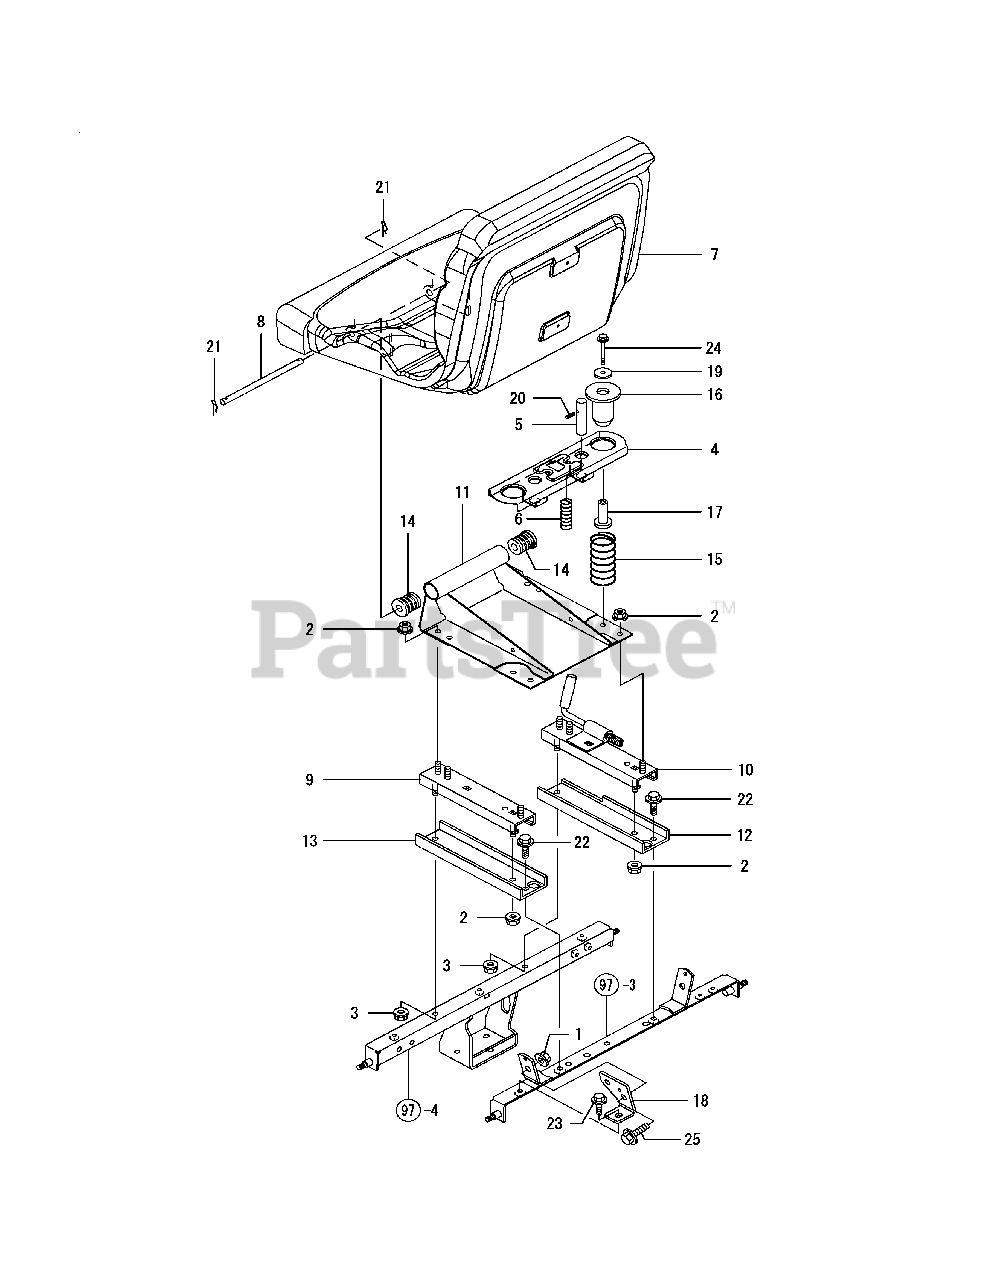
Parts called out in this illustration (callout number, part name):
1	NUT, M10
2	NUT W/WASHER 8
3	NUT W/WASHER 8
4	BKT (SEAT SPRING)
9	ADJUSTER, BELT
10	ADJUSTER, BELT
11	LOWER BRACKET, SEAT
15	SPRING, CUSHION
16	RUBBER, CUSHION
18	STAY, SEAT BELT L
19	WASHER 8.5X22X2.3
20	SPRING PIN 3X25
22	BOLT M 8X 16 PLATED
23	BOLT M 8X 20 PLATED
24	BOLT M 8X 70 PLATED
25	BOLT M10X 25 PLATED
